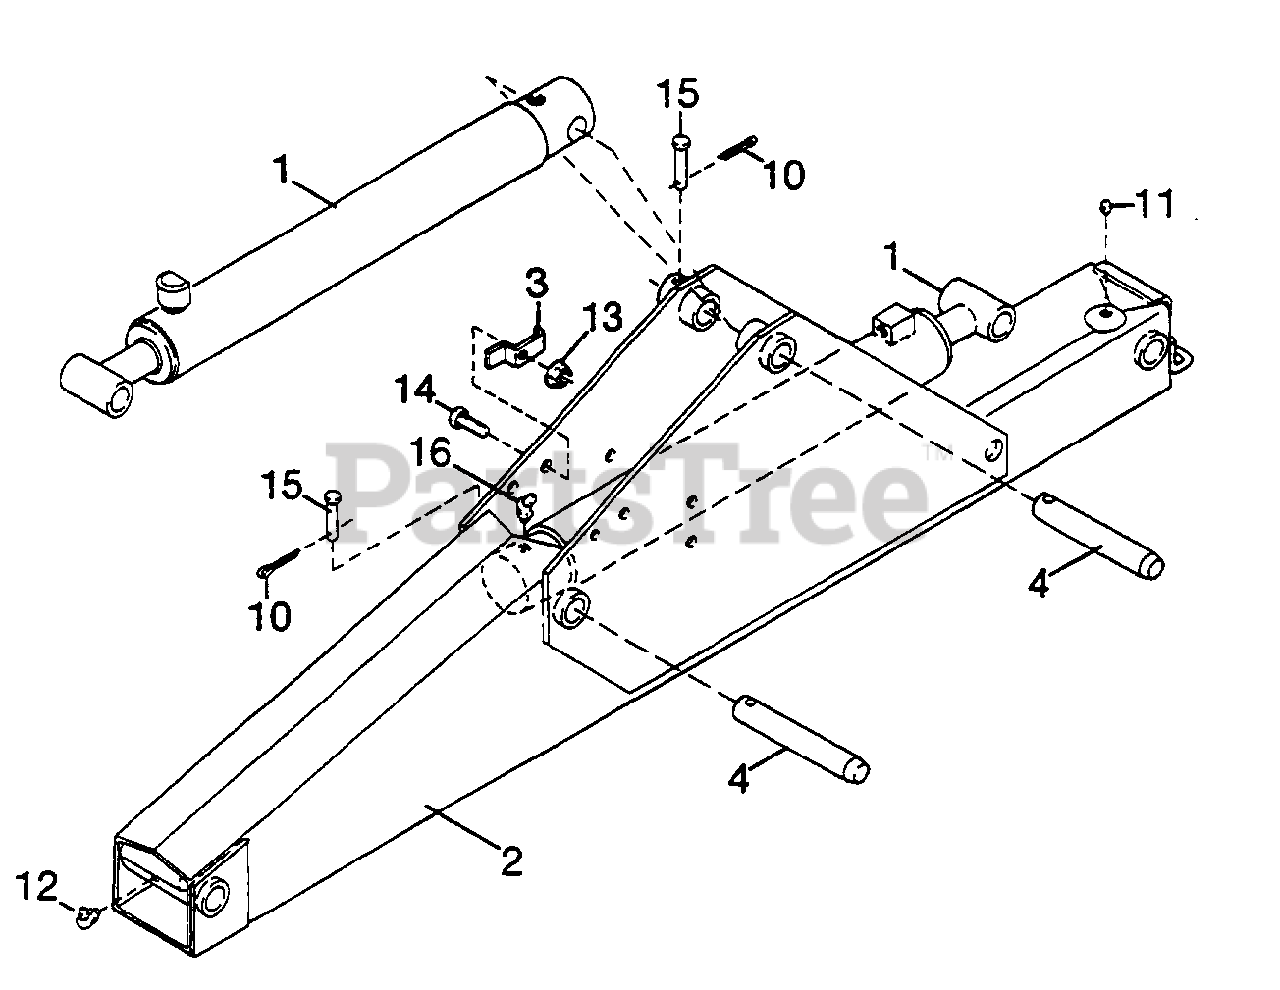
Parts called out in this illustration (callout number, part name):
1	2-1/2 x 16-3/4 Hydraulic cylinder assembly
2	Boom weldment assembly
3	Cylinder hose clamp
4	Pin, Pivot 6-1/4 x 1"
10	1/16 x 1/2 Cotter pin
11	1/4 - 28 Tapered thread grease fitting
12	1/4 - 28 Threaded 90° grease fitting
13	1/4 NC Flanged hex locknut
14	1/4 NC x 1-1/4 Hex head cap screw GR5
15	1/4 x 1-7/8 Clevis pin
16	1/4 - 28 Threaded 45° grease fitting
